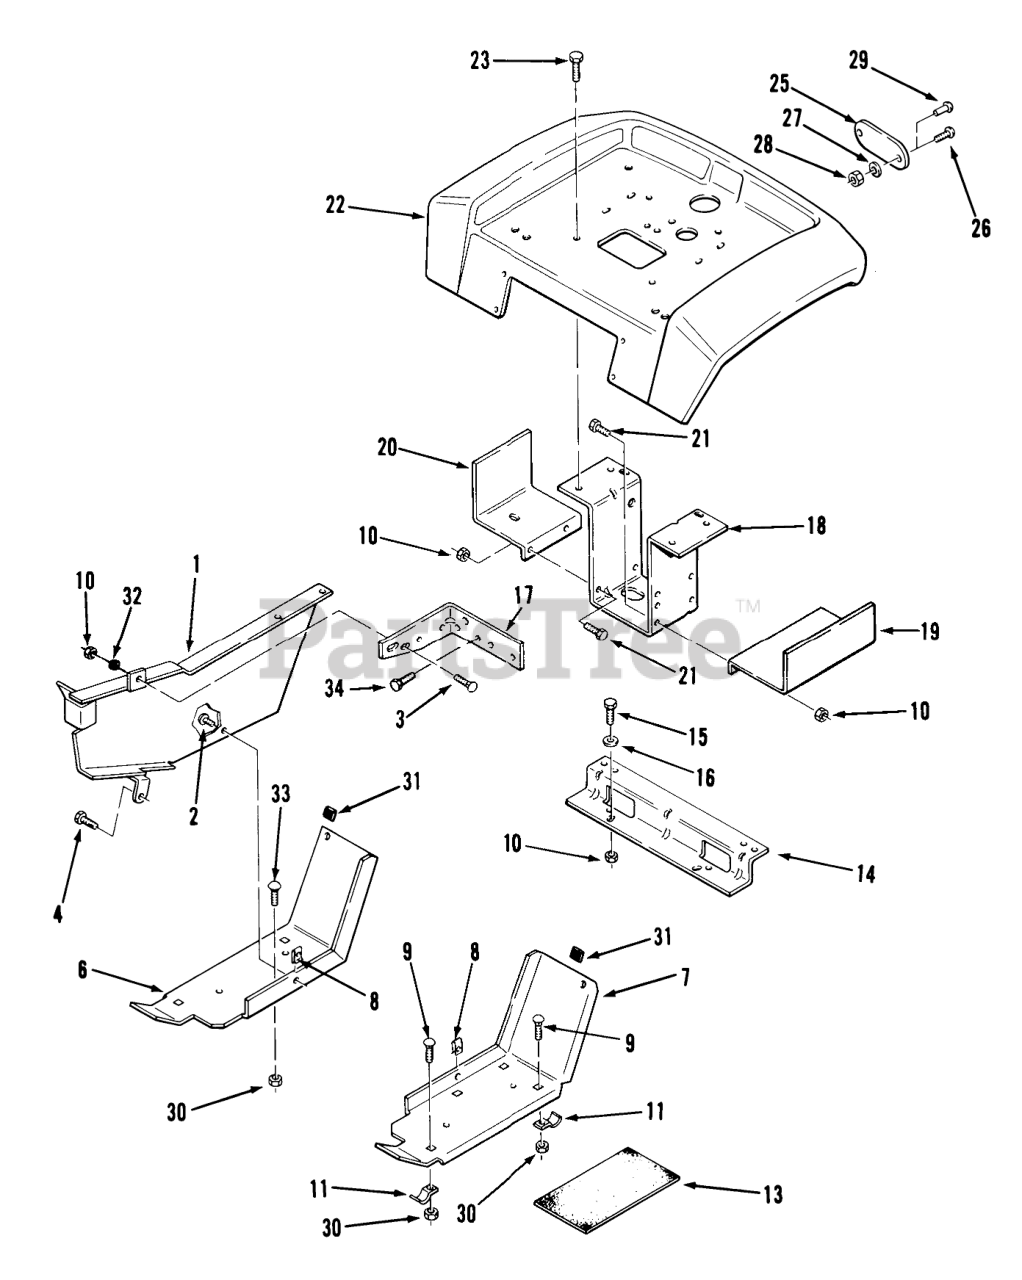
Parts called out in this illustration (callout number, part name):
1	Belt Guard
2	Screw
3	Bolt
4	SCREW
6	Footrest-RH
7	FOOTREST LH R
9	Bolt
10	Nut
11	BRACKET
13	PAD-FOOTREST
13	PAD FOOTREST
13	LH FOOTREST MAT
13	RH FOOTREST MAT
14	BRACKET-FENDER B
14	Bracket-Fender
15	Bolt
16	WASHER 5/16 SAE
17	BRACKET-BELTB
18	Bracket-Fender Support
19	Fuel Tank Support LH
20	Support-FueITank RH
21	Bolt
22	Fender
23	SCREW
24	WASHER 5/16 SAE
25	Reflector
26	Screw
27	Lockwasher
28	Nut
29	Poprivet
30	Nut
31	BUMPER
32	NUT-PUSH
33	Bolt-Carriage
34	Bolt
